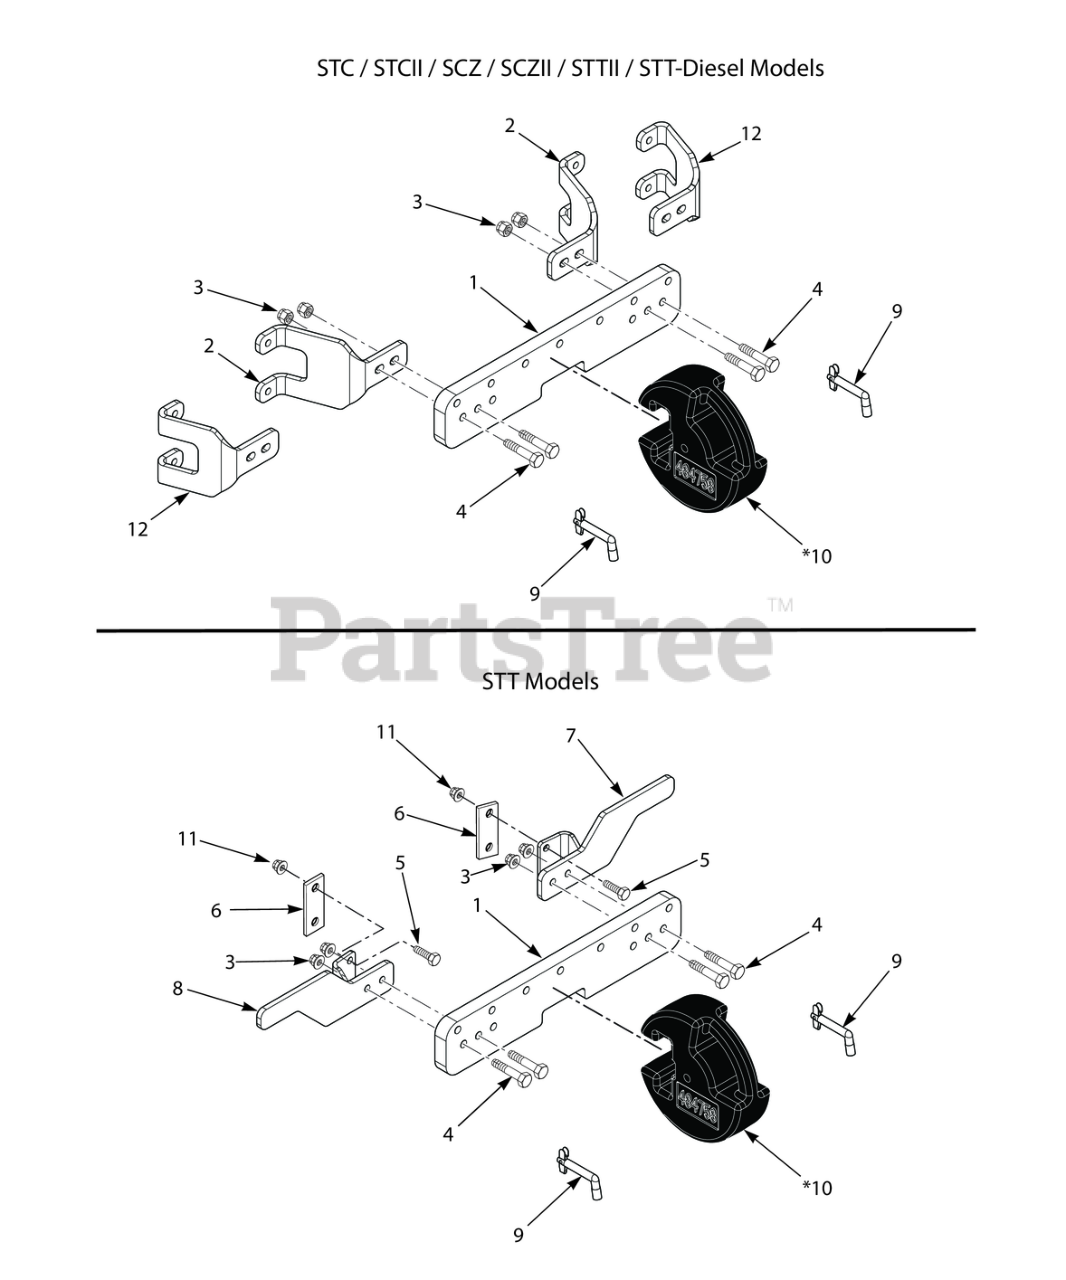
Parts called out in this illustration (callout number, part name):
1	Weight Bar
2	Bracket, LH Weight Bar (STC / STCII & SCZ48/52)
2	Bracket, RH Weight Bar (STC / STCII & SCZ48/52)
2	Bracket, Weight Bar (LH & RH for STT-Diesel, STTII52/61 & SCZ61)
3	Nut, Elastic Stop 1/2-13, (STT-52 & STTII-52)
4	HEX HD. BOLT 1/2-20 X 2 SPECIAL
5	Bolt, Hex Head, 3/8-16 x 1-1/2"
6	Clamp, Bar
7	Mounting Bracket Weldment, LH Weight Bar
8	Mounting Bracket Weldment, RH Weight Bar
9	Pin, Weight Retention
10	Weight
11	Nut, Flange Elastic Stop Nut, 3/8-16
12	BRKT, WEIGHT BAR
